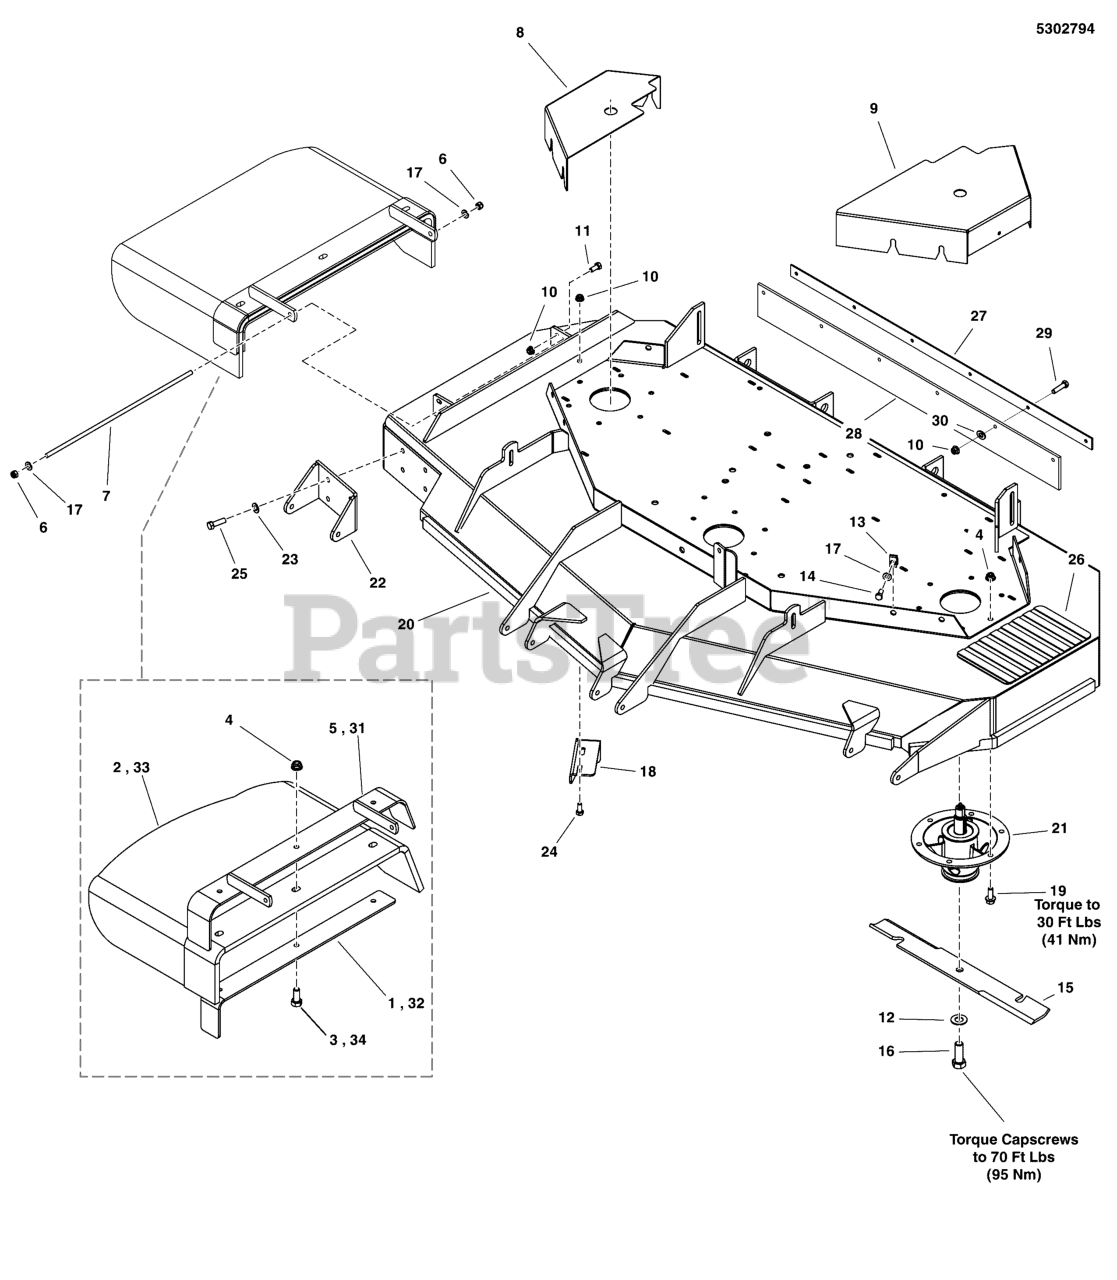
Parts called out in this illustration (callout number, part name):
1	SUPPORT, DISCHARGE CHUTE, 61/72 - BLK
2	CHUTE, DISCHARGE, BEND RUBBER (SV)
3	BOLT, 3/8-16 X 1-1/2" GD5 CZ
4	NUT, 3/8-16 HEX NYLOCK FLANGE
5	WELD, FRAME CHUTE, 61 - BLK
6	NUT, 5/16-24 HEX NYLON LOCK
7	ROD MOUNT, CHUTE 61"
8	GUARD, RH - 61 - S200XI - RED
9	GUARD, 61 - LH - RED
10	NUT, 5/16-18 HEX NYLOCK FLANGE
11	BOLT, 5/16-18 X 3/4 GD5
12	WASHER, 5/8 GRADE 8, YZ
13	BODY CLIP, 5/16-18-7GA MATERIAL
14	BOLT, 5/16-18 X 3/4 GD5
15	BLADE SET, 61 DECK (3)
16	BOLT, 5/8-11 X 1-3/4 GD8
17	WASHER, 5/16" SAE
18	PLATE, DEFLECTOR - BLK
19	BOLT, 3/8-16 X 1, FLANGE, GD 5, CZ
20	DECK SHELL W/ DECALS, 61", F200XT, ANSI-EXP
20	DECK SHELL W/ DECALS, 200XT 61 - FRS RED
20	DECK SHELL W/DECALS,61,200XT-FRS
21	SPINDLE ASSM, CAST IRON 8.0-6 BOLT
22	PLATE, BRACKET, ANTI SCALP - RED
23	WASHER, 3/8 SAE
24	BOLT, 5/16-18 X 3/4, CARRIAGE
25	BOLT, 3/8-16 X 1-1/4" GD5 CZ
26	SAFETY WALK, 9.75 X 6.00
27	PLATE, SUPPORT - BLK
28	FLAP, STRIPER, 61 DECK, IS3100 S200X
29	BOLT, 5/16-18 X 1 GD5 YZ
30	5/16 PUSH-ON NUT RETAINER, STL, CZ
31	MOUNT
32	SUPPORT, DISCHARGE CHUTE - BLK
33	CHUTE, RUBBER DISCHARGE (5104442)
34	BOLT, 3/8-16 X 1-1/2, CARRIAGE, GD5, CZ
